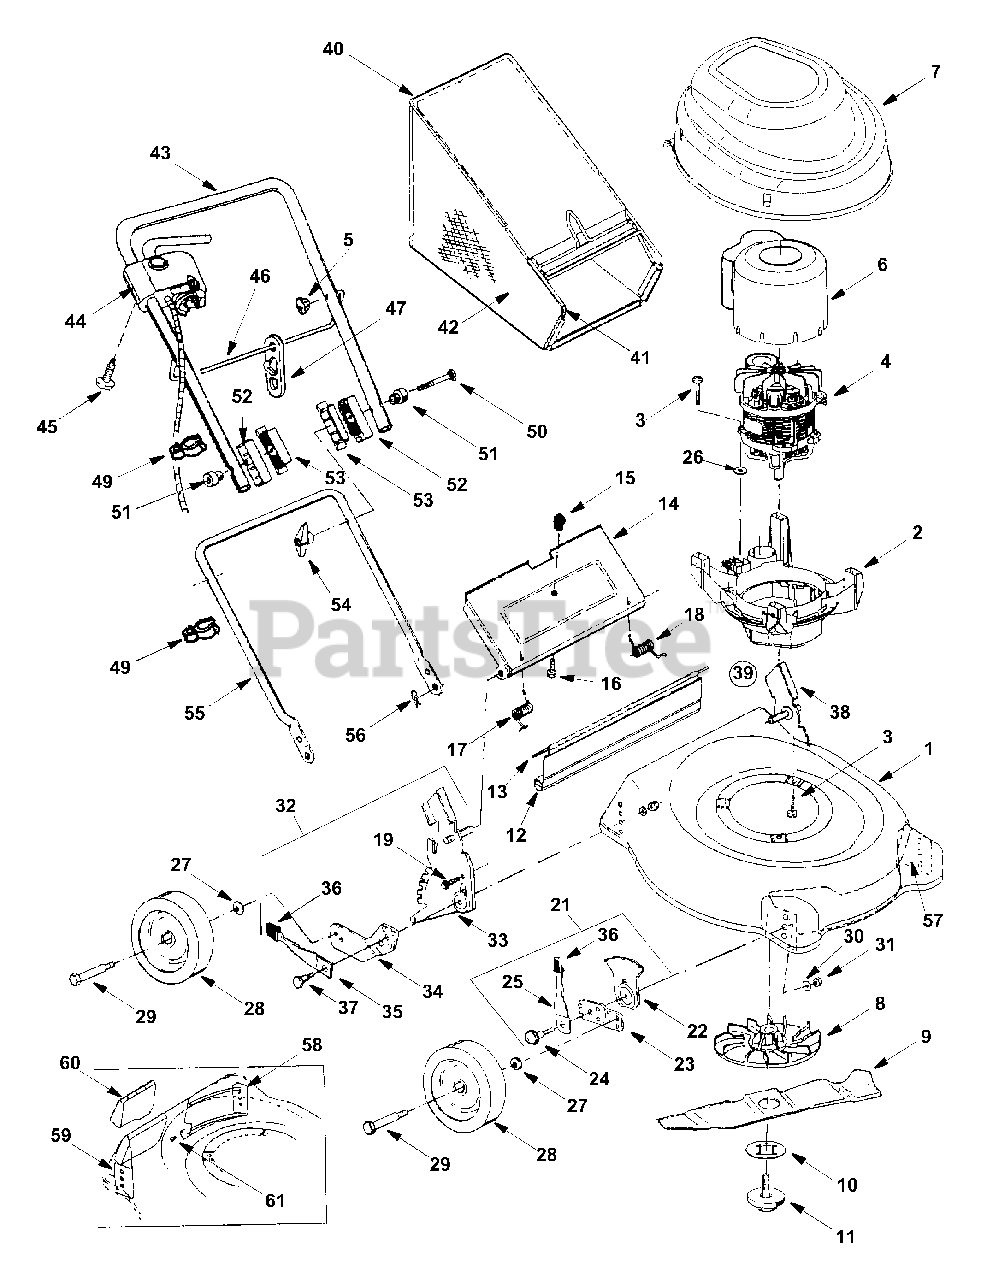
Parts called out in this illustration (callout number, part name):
1	19" Deck Red
2	Motor Base
3	Screw, M7 x 25
4	Electric Motor, 115V, 1500W
5	Wing Nut
6	Air Guide Cover
8	Blade Hub Assembly
9	Cutting Blade (Mulch/Bag)
10	Blade Locking Plate
11	Blade Screw
12	Trailing Shield
13	Wire Rod
14	Rear Discharge Door
16	Truss Screw, 10-24 x .38"
17	Door Spring, RH
18	Door Spring, LH
19	Washer Hd Screw, 1/4-14 x .625
21	Height Adj. Assy. RH
22	Adjusting Plate
24	Shoulder Bolt
25	Lever and Knob Assy.
26	Washer
27	Bell Washer
28	Wheel
29	Axle Bolt
30	Bell Washer
32	Handle Bracket Assy, RH
33	Handle Bracket, RH
34	Pivot Bar, RH
35	Spring Lever
36	Height Adjustment Knob
37	Shoulder Bolt
38	Handle Bracket, LH
39	Handle Bracket Assy, LH
42	Grass Bag
45	Screw
46	Cord Control Rod
49	Cable Guide
50	Carriage Bolt
51	Insulating Knob Spacer
52	Upper Handle Insulator
53	Lower Handle Insulator
54	Handle Knob
57	Front Baffle
58	Rear Baffle
59	Rear Mulch Baffle
60	Rear Mulch Plug
61	Tap Screw, 1/4-14 x .625"
